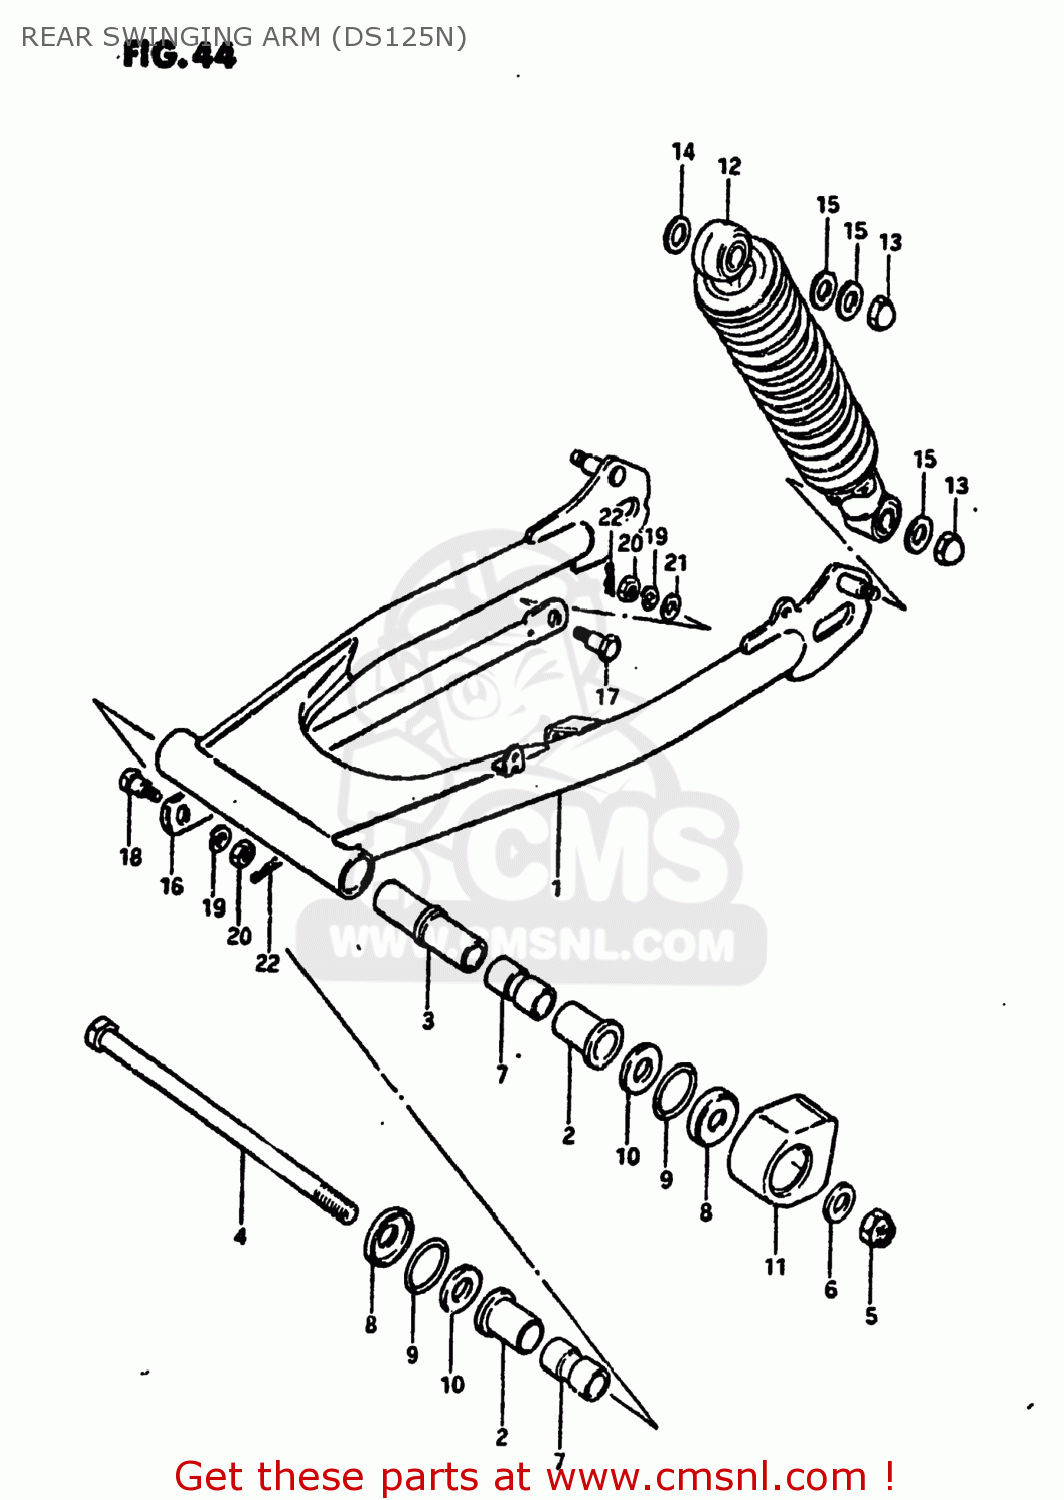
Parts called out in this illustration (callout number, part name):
1	SWING ARM ASSEMBLY,REAR
2	BUSH
3	SPACER,RR SWGARM PIVOT CTR
4	SHAFT,REAR SWING ARM
5	NUT
6	WASHER
7	SPACER,RR SWGARM PIVOT
8	COVER,SWGARM BUSH DUST SEAL
9	O RING(D:2,ID:24.5)
10	WASHER(12.5X24X2.3)
11	BUFFER,CHAIN TOUCH DEFENSE
12	ABSORBER ASSEMBLY,REAR SHOCK
13	NUT, LOWER LH
14	WASHER
15	WASHER
16	TORQUE LINK,REAR
17	BOLT(8X22)
18	BOLT(8X26.5)
19	LOCK WASHER
20	NUT
21	WASHER
22	CLIP
